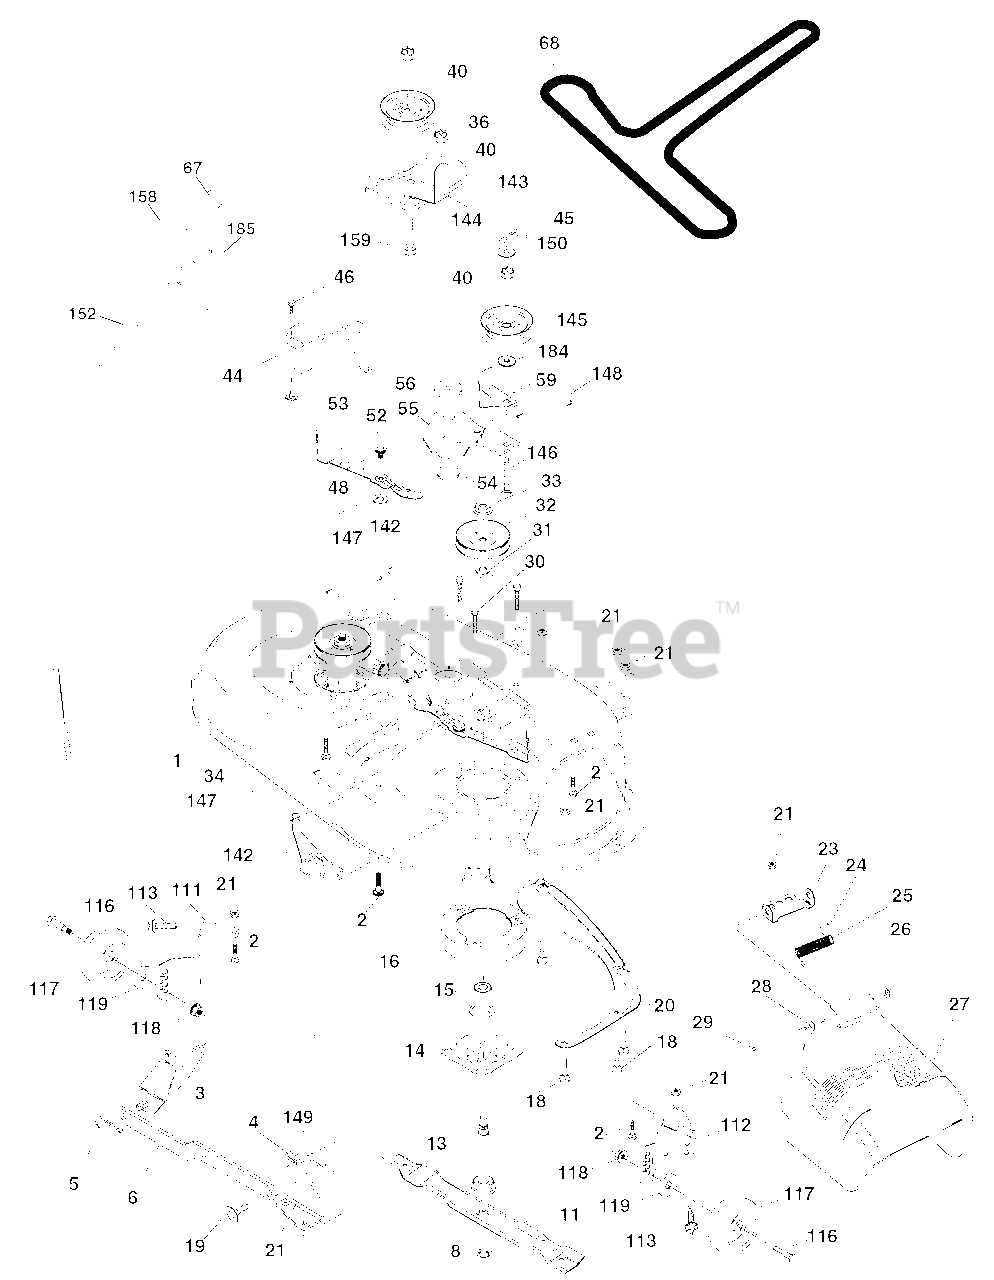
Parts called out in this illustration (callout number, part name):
1	Mower Deck Assembly, 42"
2	Bolt
3	Bracket Asm. Fr. Sway Bar 3/42
4	Bracket Asm. Deck 42" Sway Bar
5	Retainer Spring
6	Bar Sway Deck
8	Bolt/Washer Asm. 7/16-20 unf (The following Blades are available)
11	Blade Mower 42” Hi-Lift (for bagging and discharging)
11	Blade, Mulching 42” Std. (for mulching mowers only)
11	Blade Mulching 42” Premium (For better wear when mulching)
13	Shaft As m. Mandrel
14	Housing, Mandrel
15	Bearing, Ball, Mandrel
16	Stripper, Mandrel Deck
18	Bolt, Carriage 5/16-18 x 5/8
19	Bolt, Shoulder
20	Baffle, Vortex
21	Nut
23	Bracket, Deflector Mower 42"
24	Cap, Sleeve 80 x 112 Blk. Mower
25	Spring, Torsion, Deflector 2 52
26	Nut, Push Phos. & Oil
27	Shield, Deflector 42" Blk.
28	Washer 11/32 x 5/8 x 16 Ga.
29	Rod, Hinge 42" 6 75 W/G
30	Screw Thdrol.
31	Washer, Spacer Mower Vented
32	Pulley, Mandrel
33	Nut, Toplock
34	Bolt Carr. SH 3/8-16 x 1-1/2 Gr. 5
36	Pulley, Idler, Flat
40	Nut Lock 3/8-16
44	Guard, Mandrel, LH
45	Retainer
46	Screw, Thdrol. 1/4-20 x 5/8 T
48	Washer, Hardened
52	Bolt, Shoulder 5/16-18 unc
53	Arm Assembly, Pad, Brake
54	Washer, Hardened
55	Arm, Idler
56	Spacer, Retainer
59	Guard TUV Idler
67	Knob Round
68	V-Belt, 42" Mower
92	Nut Lock Hex
111	Bracket Wheel Gauge LH
112	Bracket Wheel Gauge RH
113	Bolt 5/16-18 Hex
116	Bolt SHLD
117	Wheel Gauge
118	Nut Centerlock 3/8-16
119	Washer 3/8 x 7/8 x 14 Ga.
129	Washer 13/32 x 13/16 x 12 Ga.
130	Bolt Fin Hex
131	Bolt Rdhd. Sqnk.
142	Arm Spring Brake Mower
143	Bracket Arm Idler 42"
144	Keeper Belt 42" Clutch Cable
145	Pulley Idler Flat
146	Bolt Carriage Idler
147	Spring Extension
148	Spring Return Idler
149	Retainer Spring Yellow
150	Washer 9/32 x 3/4 x 10 Ga.
152	Clutch Cable 42"
158	Screw Hex Thd. Cut 1/4-20 x 1/2
159	Bolt Rdhd. Sqnk. 3/8-16 unc x 1-3/4
184	Washer 13/32 x 7/8 x 10 Ga.
185	Head Asm. Cable Clutch
185	Mandrel Assembly
185	Replacement Mower, Complete
